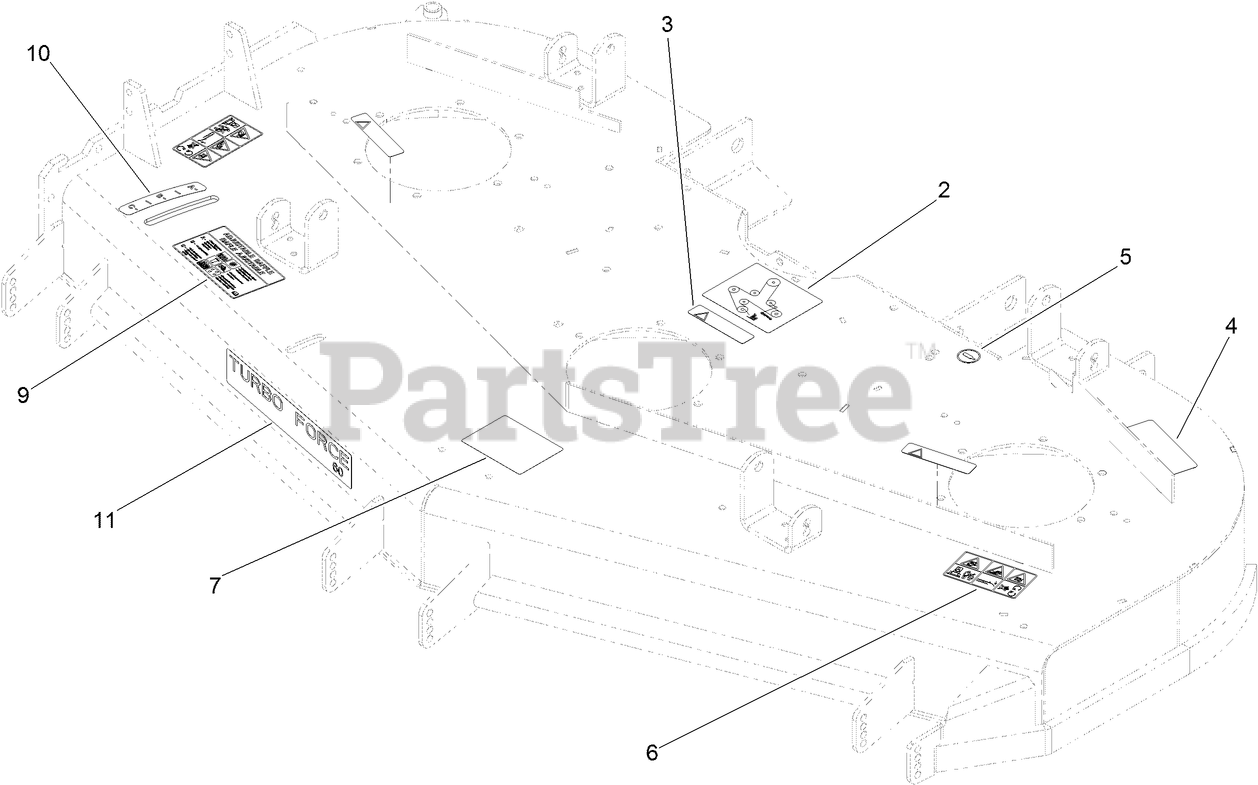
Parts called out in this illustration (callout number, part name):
2	DECAL-ROUTING, BELT
3	DECAL-WARNING
4	DECAL-TORQUE, BLADE BOLT
5	DECAL-GREASE
6	DECAL-DANGER
7	DECAL-ANTI SCALP
9	DECAL-ADJUSTMENT, BAFFLE
10	DECAL-SETTING, BAFFLE
